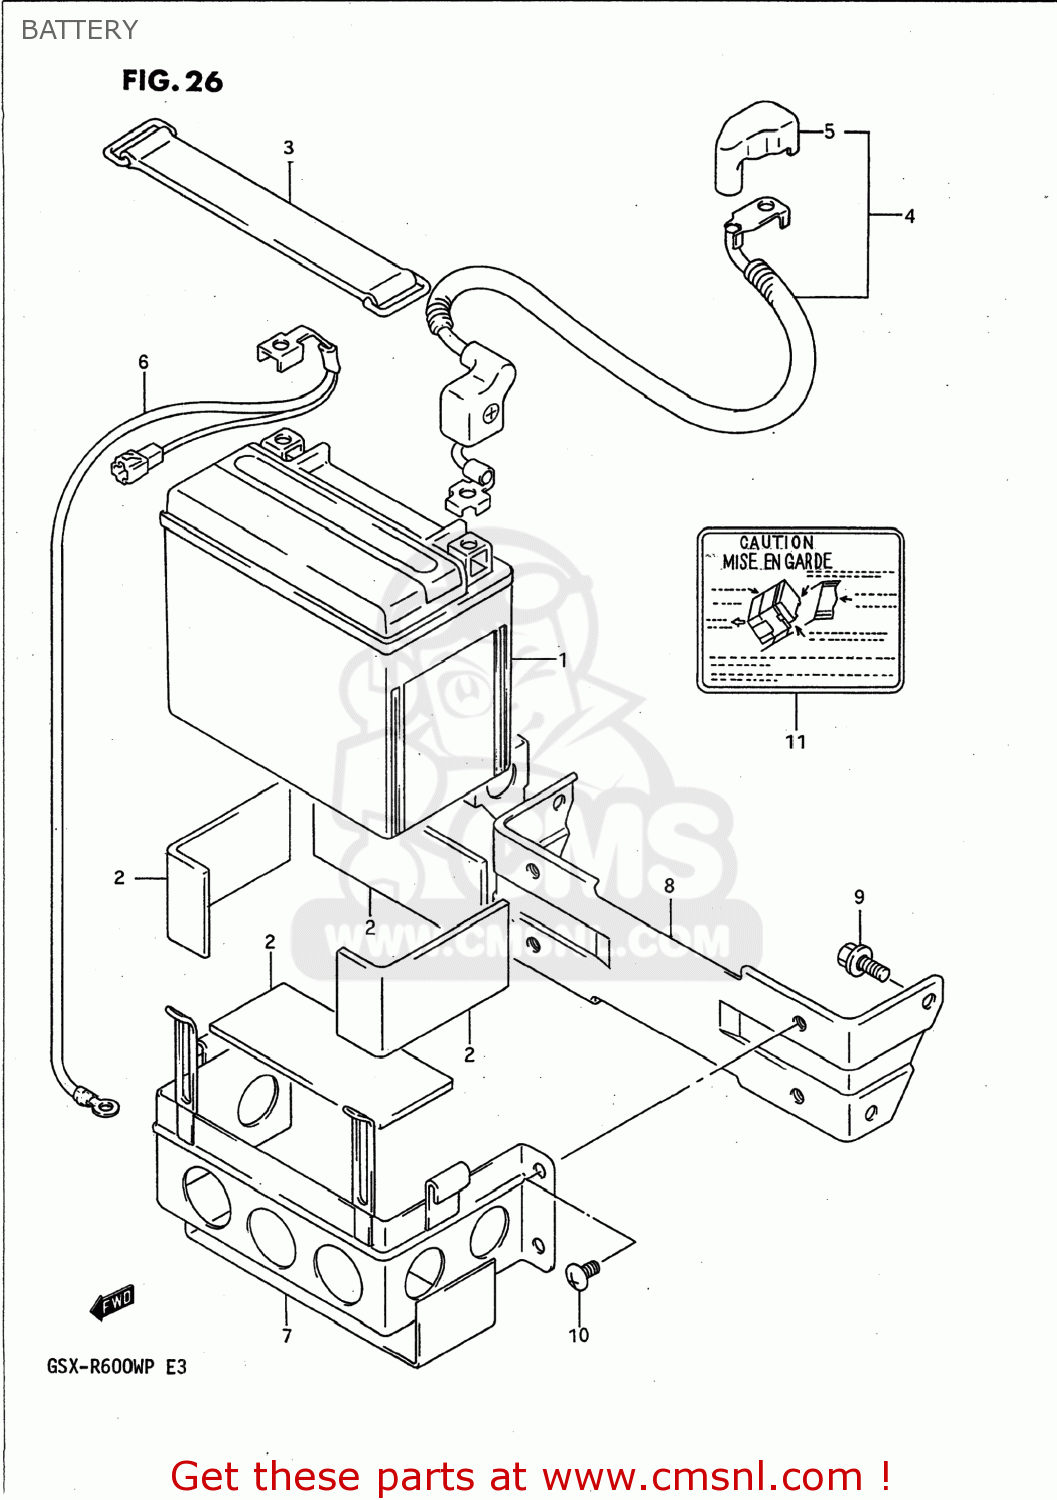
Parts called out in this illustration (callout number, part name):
1	BATTERY ASSEMBLY (12V) YTX
2	PROTECTOR(170X95X3.0)
3	BAND
4	WIRE,BATTERY PLUS
5	CAP,STARTER RELAY TERMINAL
6	WIRE,BATTERY MINUS LEAD
7	HOLDER,BATTERY
8	BRACKET,BATTERY HOLDER
9	BOLT
10	SCREW 6X12
11	PROTECTOR,BATTERY
12	PLATE,BATTERY CAUTION
